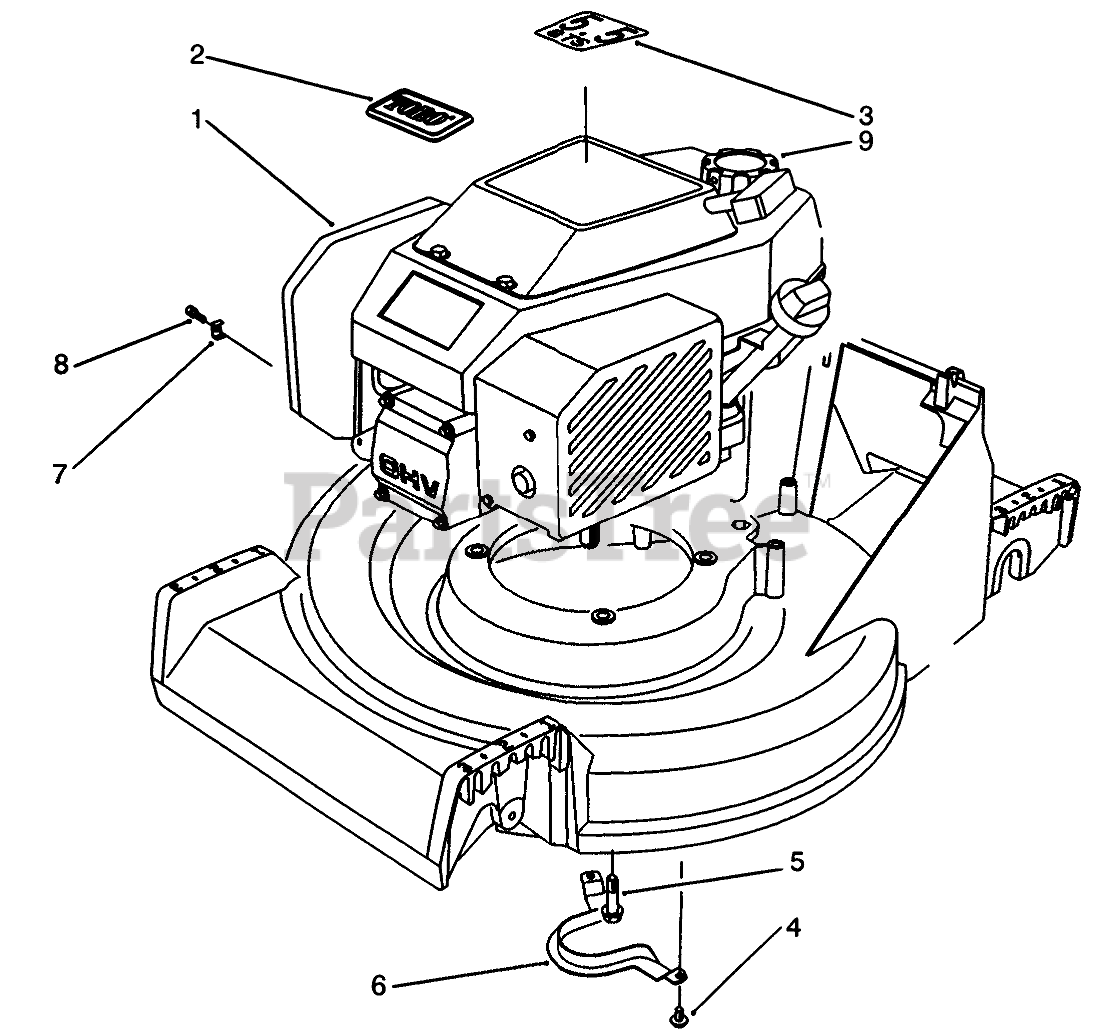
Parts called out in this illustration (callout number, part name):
4	SCREW-HWHTF
5	SCREW-HWH
7	CLAMP-CASING
9	GAS CAP ASM
